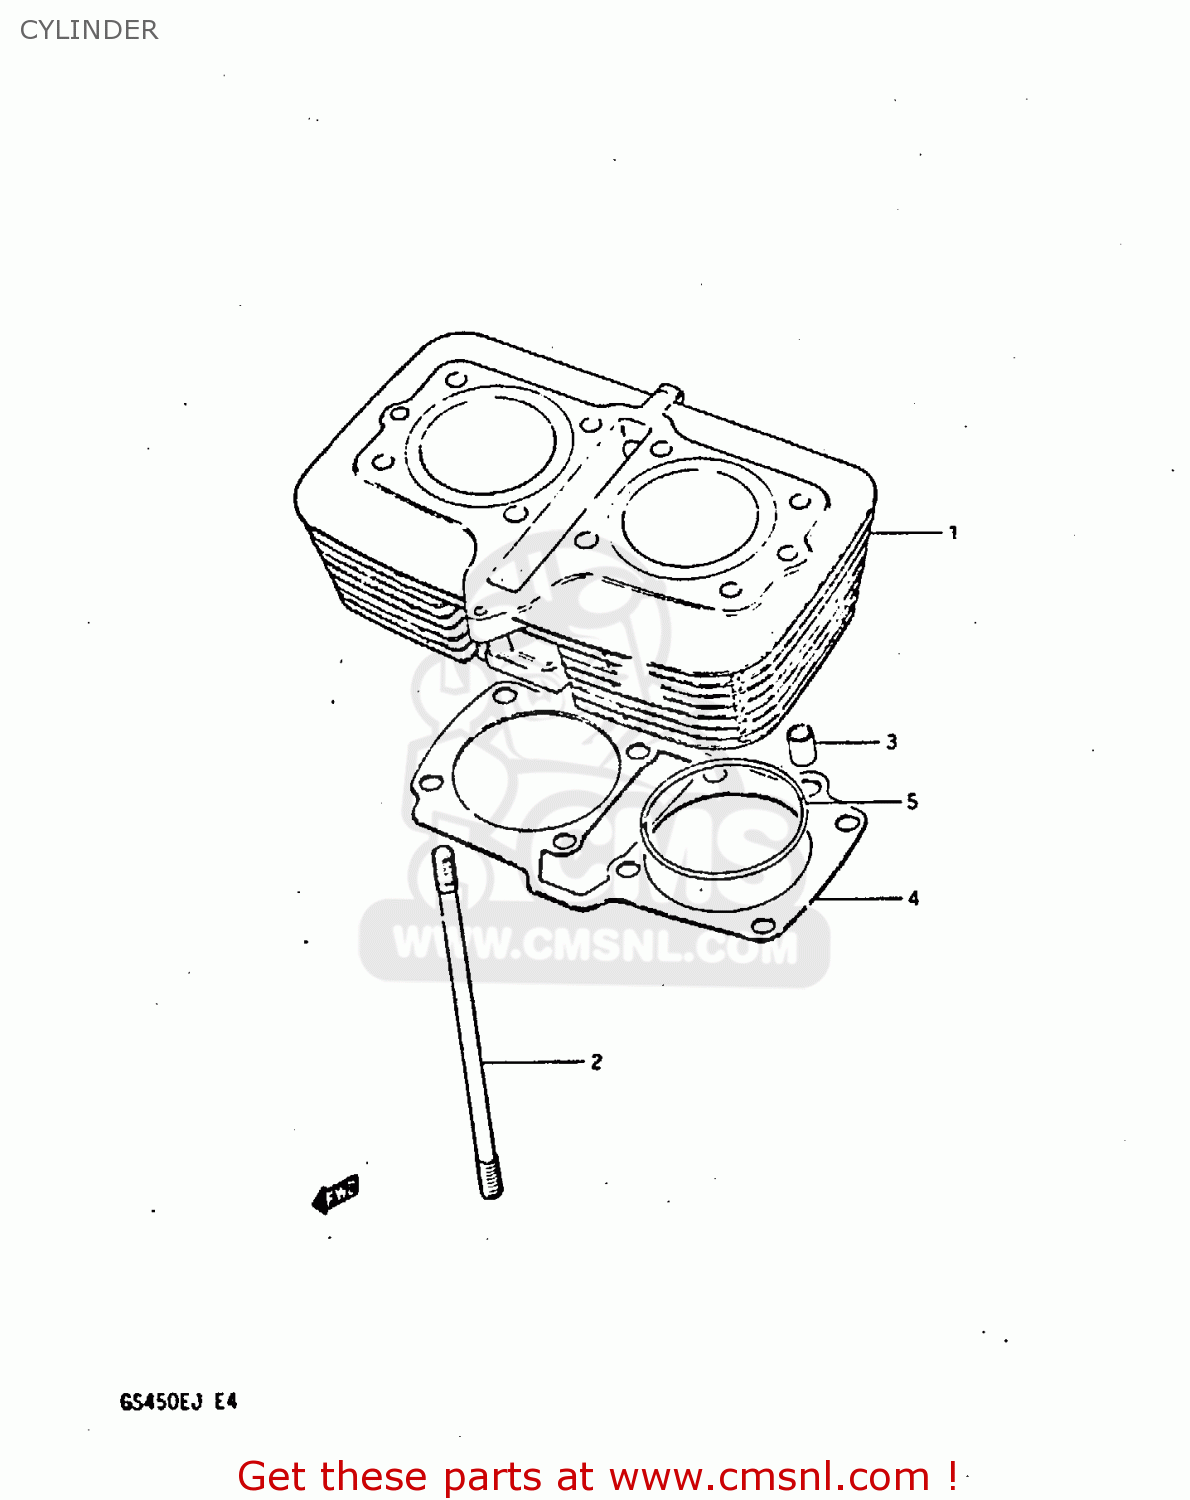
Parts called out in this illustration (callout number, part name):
1	CYLINDER
2	STUD
3	PIN
4	GASKET,CYLINDER (MCA)
5	O RING(D:2,ID:74)
